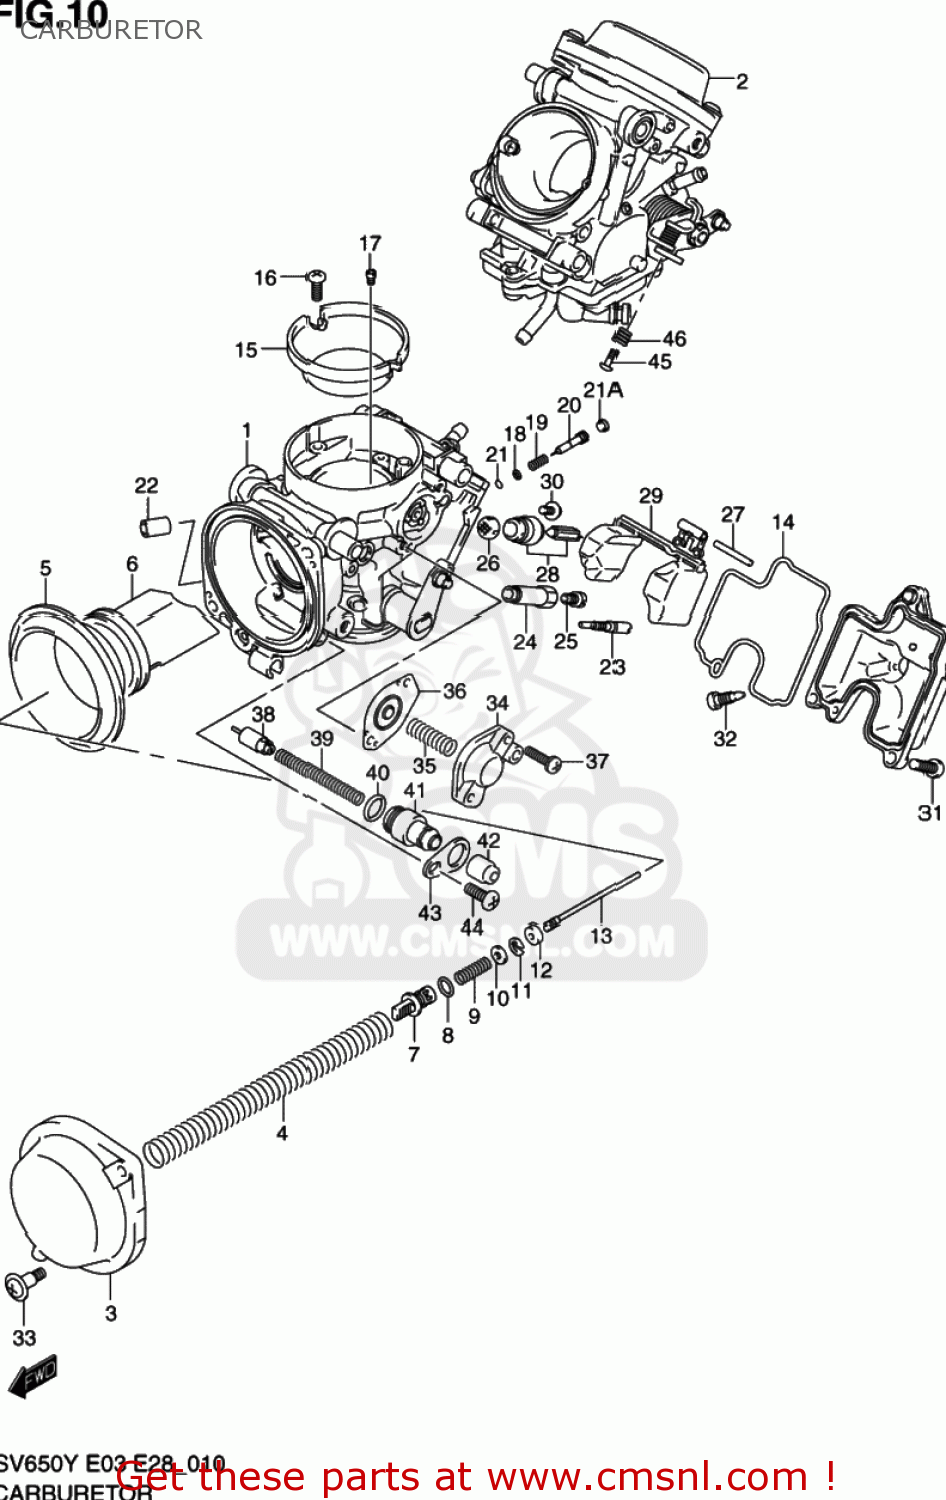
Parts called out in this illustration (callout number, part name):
1	CARBURETOR ASSY,FR
2	CARBURETOR ASSY,RR
3	COVER ASSY,DIAPHRAGM
4	SPRING
5	DIAPHRAGM
6	VALVE,PISTON
7	HOLDER
8	O RING(D:1.9,ID:4.8)
9	SPRING
10	WASHER
11	E RING,MULTIPLE JET NOZZLE
12	RING
13	JET,NEEDLE(6E42-54-1)
14	O RING
15	FUNNEL
16	SCREW
17	JET,AIR(160)
18	WASHER
19	SPRING,THROTTLE SCREW
20	ADJUSTER
21	O RING,PILOT AIR SCREW
21A	PLUG
22	CAP
23	JET,PILOT(15)
24	HOLDER,JET
25	JET,MAIN(137.5)
26	FILTER
27	PIN,FLOAT
28	VALVE ASSY,NEEDLE
29	FLOAT ASSY
30	SCREW
31	SCREW
32	PLUG,DRAIN
33	SCREW
34	COVER ASSY
35	SPRING
36	DIAPHRAGM ASSY
37	SCREW
38	PLUNGER,STARTER
39	SPRING
40	O RING
41	HOLDER,GUIDE
42	CAP
43	PLATE
44	SCREW(5X14)
45	SCREW
46	SPRING
